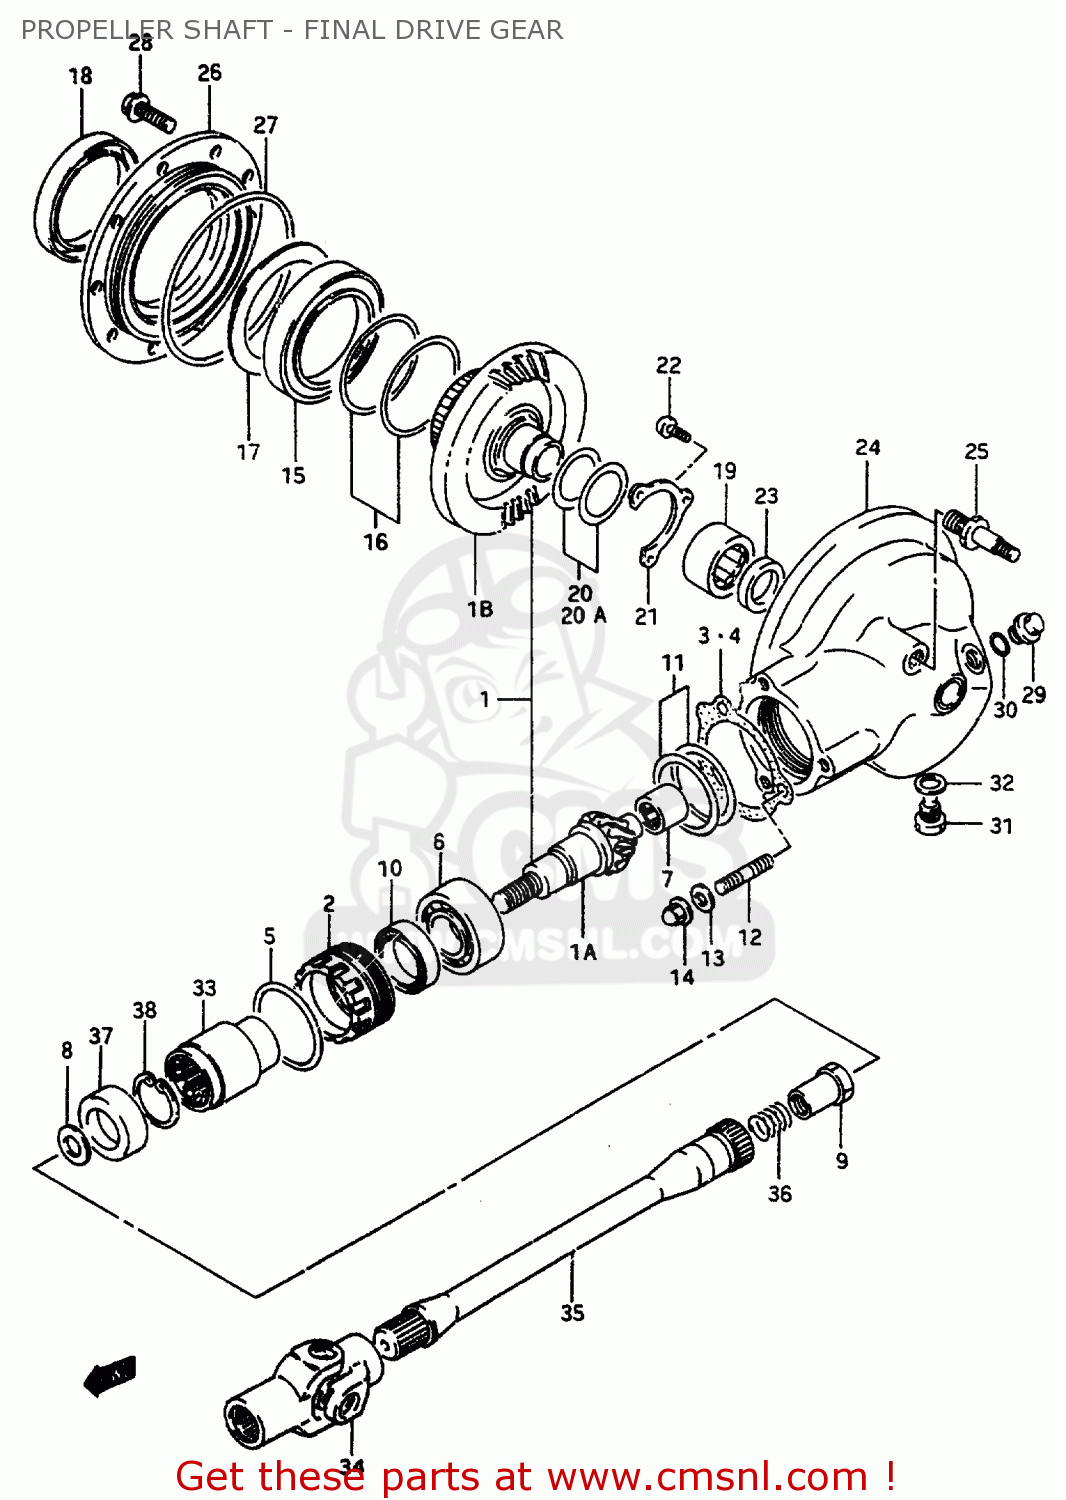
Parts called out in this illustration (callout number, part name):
1	GEAR & CASE SET,FINAL BEVEL
1A	GEAR,FINAL DRIVE BEVEL(NT:11)
1B	GEAR,FINAL DRIVEN BEVEL(NT:34)
2	STOPPER,FINAL DRIVE BEARING
3	PLATE,BEARING STOPPER
4	PLATE,BEARING STOPPER
5	O RING(D:1.9,ID:61.6)
6	BEARING(30X62X23.8)
7	BEARING(17X32X16)
8	WASHER(16X29X4)
9	NUT
10	SEAL,OIL(38X54X6)
11	SHIM SET,FINAL DRIVE GEAR
12	BOLT,STUD
13	WASHER
14	NUT
15	BEARING(70X110X13)
16	SHIM SET,DRIVEN GEAR BEARING
17	PLATE,FINAL DRIVEN BRG OIL
18	SEAL,OIL(70X96X16)
19	BEARING(32X46X17.7)
20	SHIM SET,FINAL DRIVEN GEAR
20A	SHIM SET,FINAL DRIVE GEAR
21	RETAINER,FINAL DRIVEN GEAR BRG
22	SCREW
23	SEAL,OIL(30X42X7)
24	CASE,FINAL
25	BOLT,STUD
26	CASE,FINAL GEAR BEARING
27	O RING(D:3.5,ID:131.6)
28	BOLT
29	PLUG
30	O RING(D:2.4,ID:17.8)
31	PLUG
32	GASKET(14X19.2X2) (NAS)
33	COUPLING,FINAL DRIVE GEAR
34	YOKE COMP,UNIVERSAL JOINT
35	SHAFT,PROPELLER
36	SPRING
37	SEAL,OIL(28.4X48X15)
38	CIRCLIP
